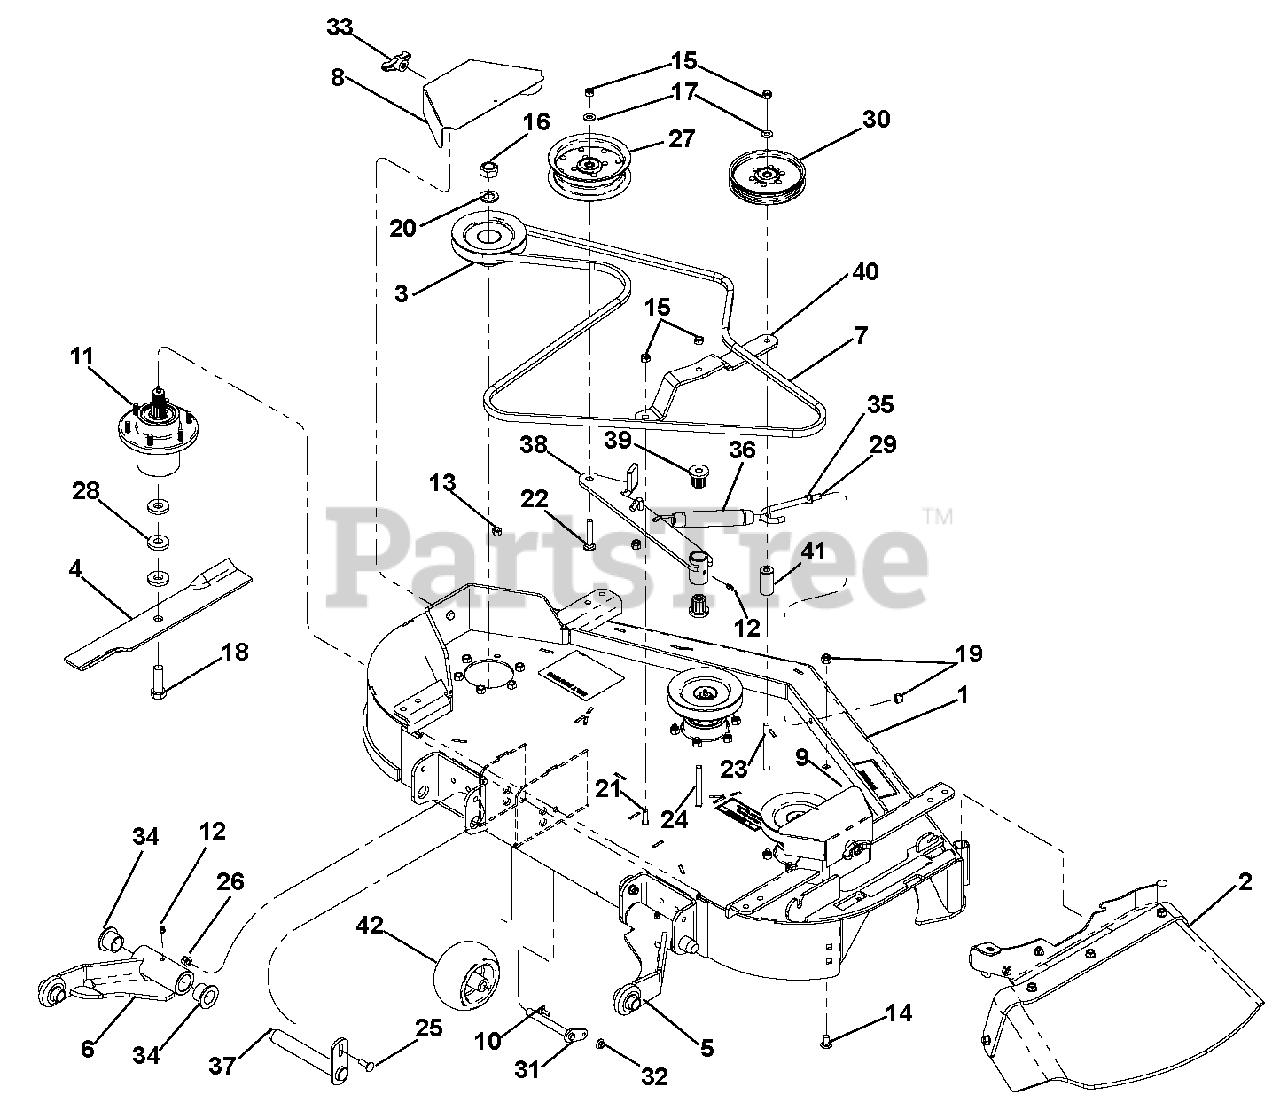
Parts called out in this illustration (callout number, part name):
1	Assembly, 48" Float Deck with Decals (994109)
2	Assembly, 48 Flat Discharge Shield (994109)
3	Pulley, Spline Spindle Offset (994109)
4	Blade, 16.50 x .80 Lift (994109)
5	Arm Weldment, RH 48" (994109)
6	Arm Weldment, LH 48" (994109)
7	Belt, HB 98.6 Elbow AMD (994109)
8	Left Hand Deck Belt Cover (994109)
9	Right Hand Deck Belt Cover (994109)
10	Bolt, Round Head Square Neck .25 - 20 x 1.00 Grade 5
11	Assembly, Spindle S/O
12	Fitting, Lubrication
13	Nut, 3/8-16 Standard Hex Grade 5
14	Bolt, Round Head Square Neck .38 - 16 x .75 Grade 5
15	Locknut, Crown 3/8-16
16	Locknut, Crown .75 - 16 Grade 5
17	Washer, Flat .406 x .813 x .065
18	Bolt, Hex 5/8-11 x 2.00
19	Locknut, Nyloc 3/8-16
20	Washer, .75 x 1.3125 x .113
21	Bolt, Round Head Square Neck .38 - 16 x 1.00 Grade 5
22	Bolt, 3/8-16 x 2.25
23	Bolt, Round Head 3/8 x 4 SHTNK
24	Bolt, .38-16 x 3.50
25	Bolt, Right Hand Square Neck, M8 x 1.25
26	Locknut, Nyloc Flange, M8 x 1.25
27	Pulley, Flat 5.00 x .375 W/ BRG
28	Washer, Flat, .630 x 1.50 x .250
29	J-Bolt, .38-16 x 4.00 (994109)
30	Pulley, Flat Idler
31	Pivot, Retainer Weldment
32	Nut, 1/4" Flange Prevailing Tor
33	Knob, .38-16 Insert
34	Bearing, Flanged
35	Locknut, 3/6-16
36	Spring, External
37	Pin, Welded
38	Arm, Idler
39	Bearing, Flange M10 x M25 x M27 Fluted
40	Strap, Idler Pulley
41	Spacer Assembly
42	Wheel, Anti Scalp 5 x 3 Center
NS	Spacer, .510 x .625 x 3.25 (Used with part number 03905900)
